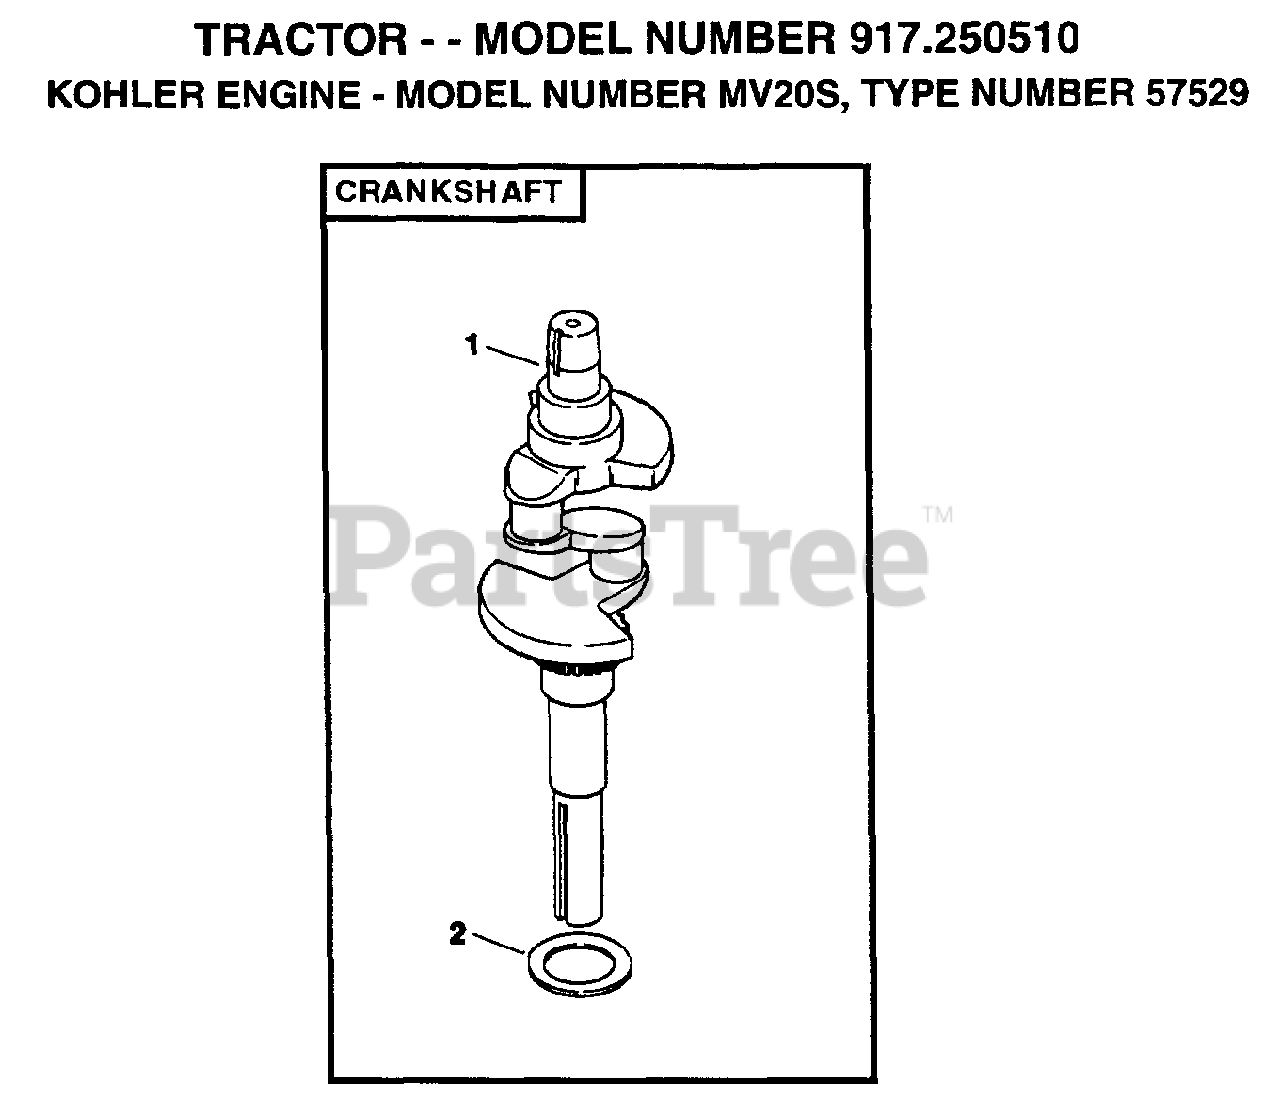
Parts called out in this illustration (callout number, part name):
2	WASHER, .119/.122 (A.R.)
2	WASHER, .128/.131
2	WASHER, .137/.140 (A.R.)
